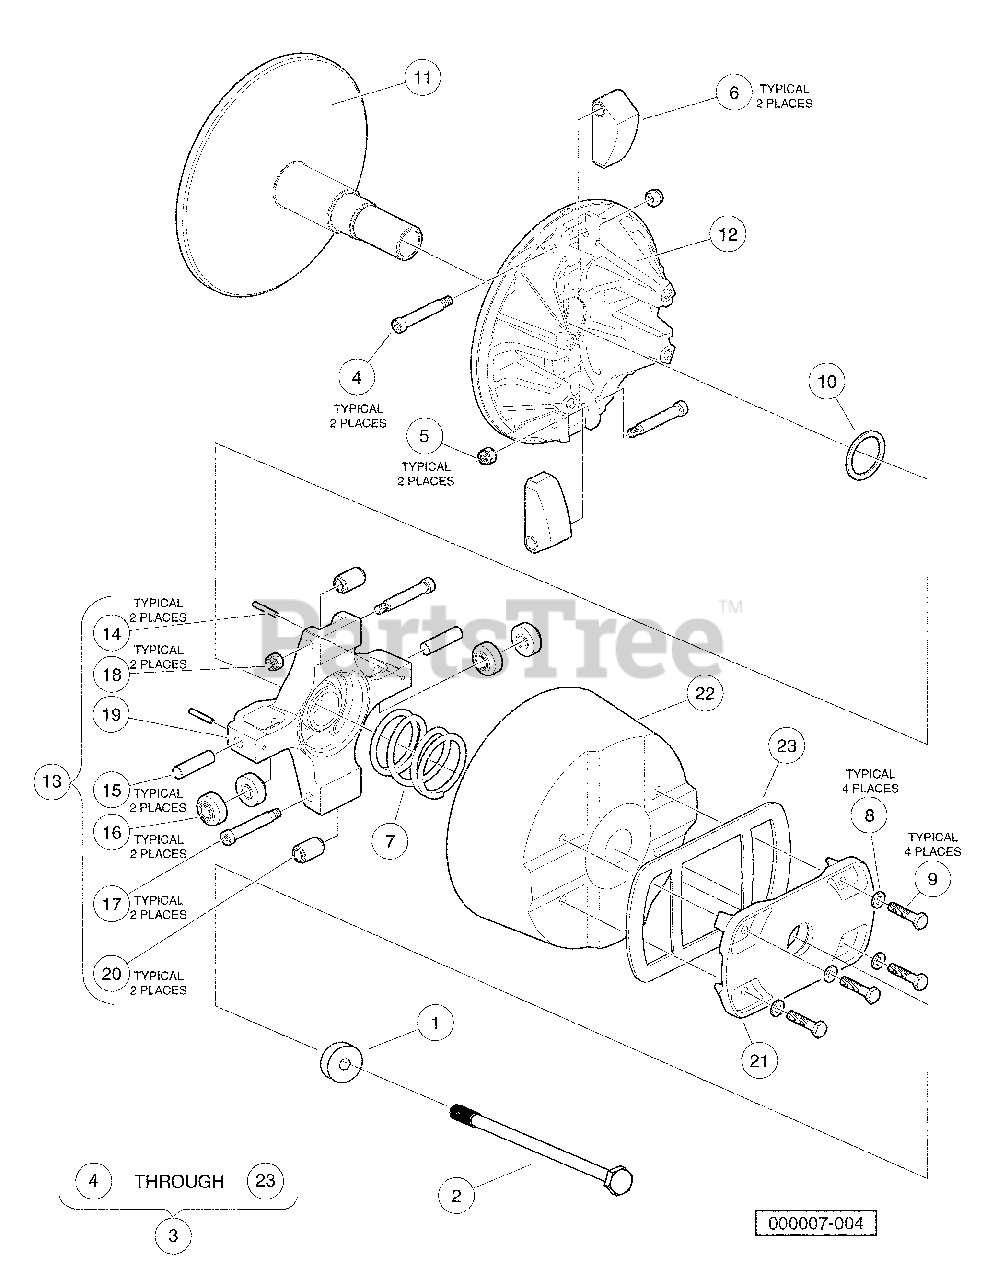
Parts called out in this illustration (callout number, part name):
1	Washer, Stepped
2	Bolt, M10 X 1.5 X 160
3	Clutch, 4x4, Diesel, W/cover
4	Screw, Shlder Hex, .312 X 1.75
5	Nut, Lock Hex, 1/14-20, Flexlc
6	Sub Assy, Wt Clutch, Diesel.
7	Spring, Compression, Primary
8	Washer, Lock, H-Spring, 1/4.
9	Screw, Cap, Hex Hd, 1/4 X 1.25.
10	Shim, 1.63 X 1.33
11	Subassembly, Drive Clutch
12	Subassembly, Moveable, Drive Clutch
13	Subassembly, Spider Utility, Diesel
14	Pin, Spring Slotted,1.25 X 1.0
15	Pin, Dowel, .375 X 1.50
16	Roller, Torque, Diesel.
17	Screw, Shlder Hex, .312 X 1.75
18	Nut, Lock Hex, 1/14-20, Flexlc
19	Spider, Drive Clutch
20	Sub Assy, Roller Weight
21	Cover, Drive Clutch
22	Cover, Clutch, 4x4
23	Gasket, Cover, Clutch, 4x4
